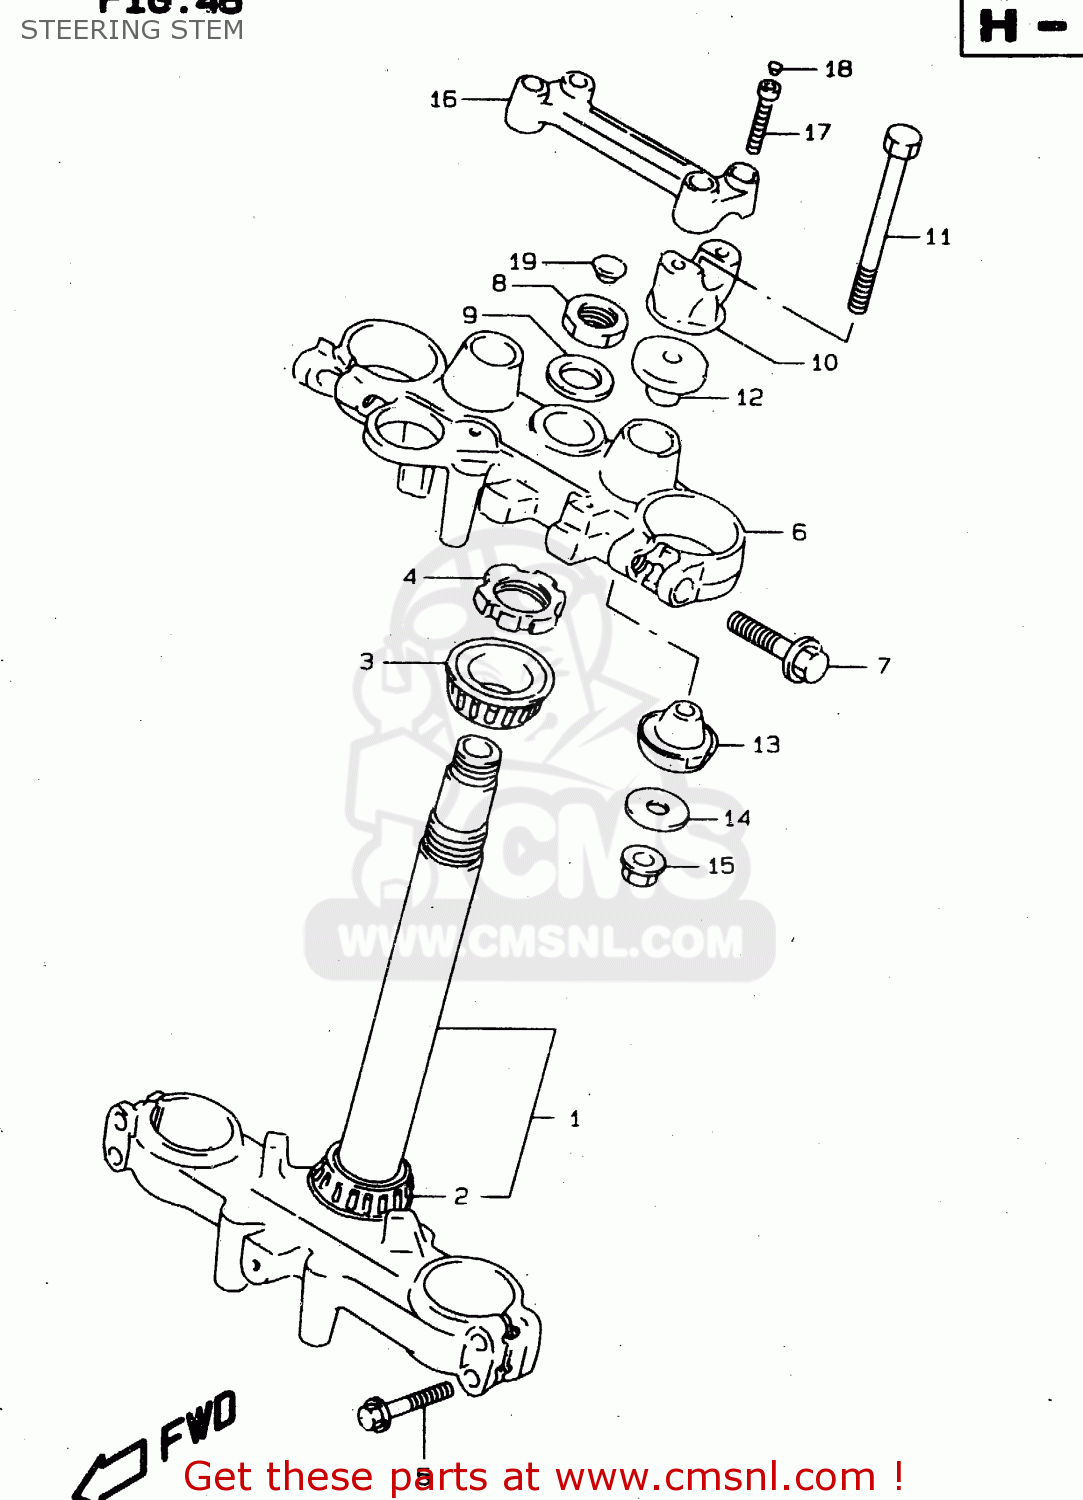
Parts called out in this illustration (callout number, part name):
1	STEM,STEERING
2	BEARING(30X52X16)
3	BEARING(30X52X16)
4	NUT,STEERING
5	BOLT
6	HEAD,STEERING STEM
7	BOLT
8	NUT
9	WASHER,STEM HEAD(24.5X34X1.6)
10	HOLDER,HANDLE LWR
11	BOLT
12	DAMPER,UPR
13	DAMPER,LWR
14	WASHER,HANDLEBAR HOLDER
15	NUT
16	HOLDER,HANDLE UPR
17	BOLT
18	CAP(OD:14.5)
19	CAP(OD:20)
